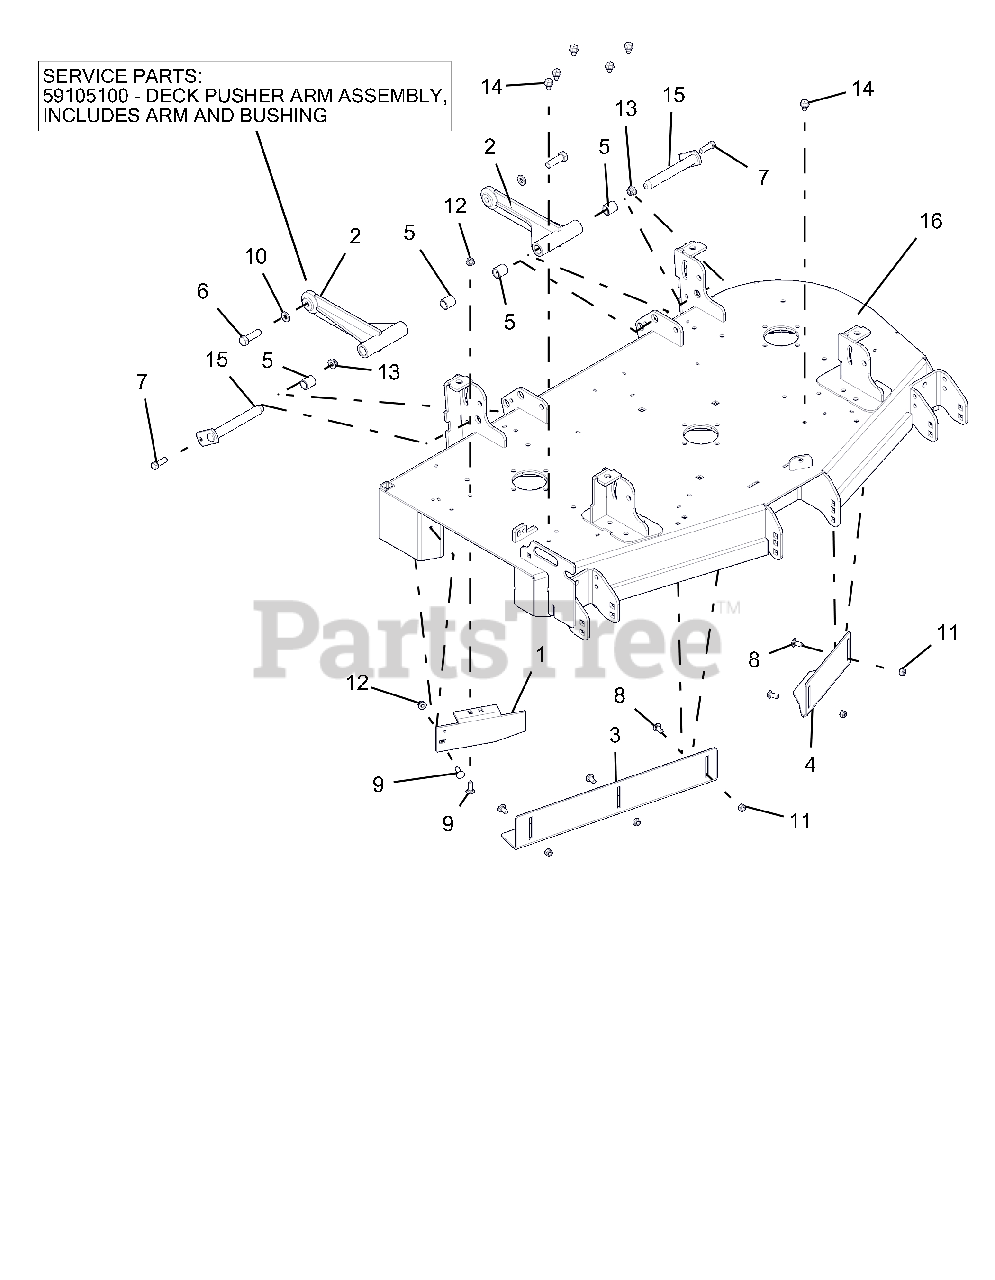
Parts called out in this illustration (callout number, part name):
1	BAFFLE, 44-48" SIDE DISCHARGE
2	WLDMT, DECK PUSHER ARM
2	DECK PUSHER ARM ASSEMBLY
3	BAFFLE, 48" RH VACUUM
4	BAFFLE, 44/48" LH VACUUM
5	BRG, .750 X .875 X 1.000
6	BLT-HEX .50-13X1.75 GR5 YWZC EP80
7	BLT-HEX .38-16X1.25 GR5 YWZC
8	BLT-RDHDSQNK .31-18X.75 G5 YWZC
9	BLT-RDHDSQSHNK .31-18X1.00 G5 Y
10	WSHR-LK .50X.125 REG YWZC
11	NUT-LK-NYL .312-18 YWZC
12	NUT-LK-NYL-FLG .31-18 YWZC
13	NUT-LK-NYL-FLG .38-16 YWZC
14	SCR-TAP .38-16X.50 HWH TR YWZ
15	WLDMT, MOWER MTG. PIN
16	KIT, PT148 MOWER DECK W/SAFETY DECALS-RED
